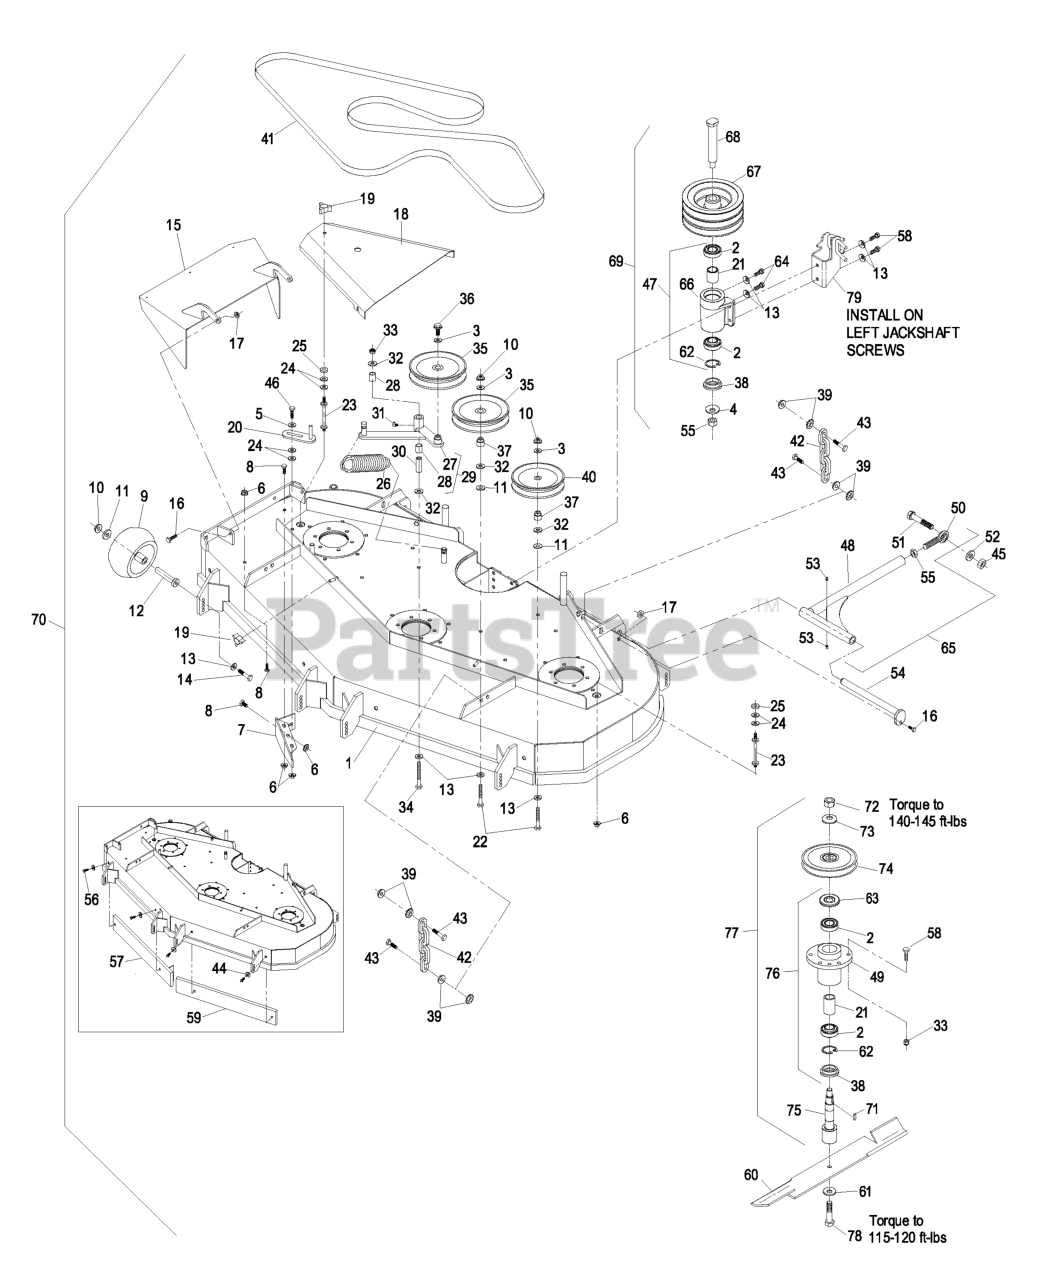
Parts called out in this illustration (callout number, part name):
2	BEARING-JACKSHAFT
3	WASHER-FLAT
4	WASHER-SPRING
5	WASHER-SPRING
7	WLD,BAFFLE DISCHARGE
8	SCREW-HH
9	ROLLER-SCALP, ANTI
10	NUT-HHF, WHIZ
12	BUSHING-ROLLER
13	WASHER-BELLEVILLE
14	SCREW-HH
16	SCREW-HH
17	NUT-LOCK, NI
18	SHIELD,BELT
19	KNOB-3 PRONG
20	GUIDE-BELT
21	SPACER-BEARING
22	SCREW-HH
23	STUD-SHIELD, BELT (SHORT)
24	WASHER-FLAT
28	SLEEVE-BEARING
30	BUSHING
31	FITTING-GREASE, 90 DEG
32	WASHER-FLAT
33	NUT-LOCK, NI
34	SCREW-HH
36	SCREW-HHF
37	BUSHING-IDLER
38	SPACER-GUARD, BOTTOM
40	PULLEY-IDLER
41	BELT,BLADE DRIVE
42	CHAIN-LIFT, DECK
43	SCREW-HH
44	WASHER-SPRING
45	NUT-HEX
46	SCREW-HH
50	BALLJOINT-SPHERICAL
51	SCREW-HH
52	WASHER-LOCK
53	FITTING-GREASE
54	PIN-STRUT
55	NUT-HEX
56	SCREW-HH
57	WEIGHT BAR ASM
58	SCREW-HH
61	WASHER-BLADE BOLT, HEAVY
62	RING-SNAP
63	GUARD-BEARING, TOP
64	SCREW-HH
65	STRUT ASM
68	JACKSHAFT,LAZER XP
69	ASM,JACKSHAFT
70	Complete Deck Assy
74	SHEAVE,BLADE DRIVE 6.30
75	SPINDLE,SHORT
78	SCREW-CAP
